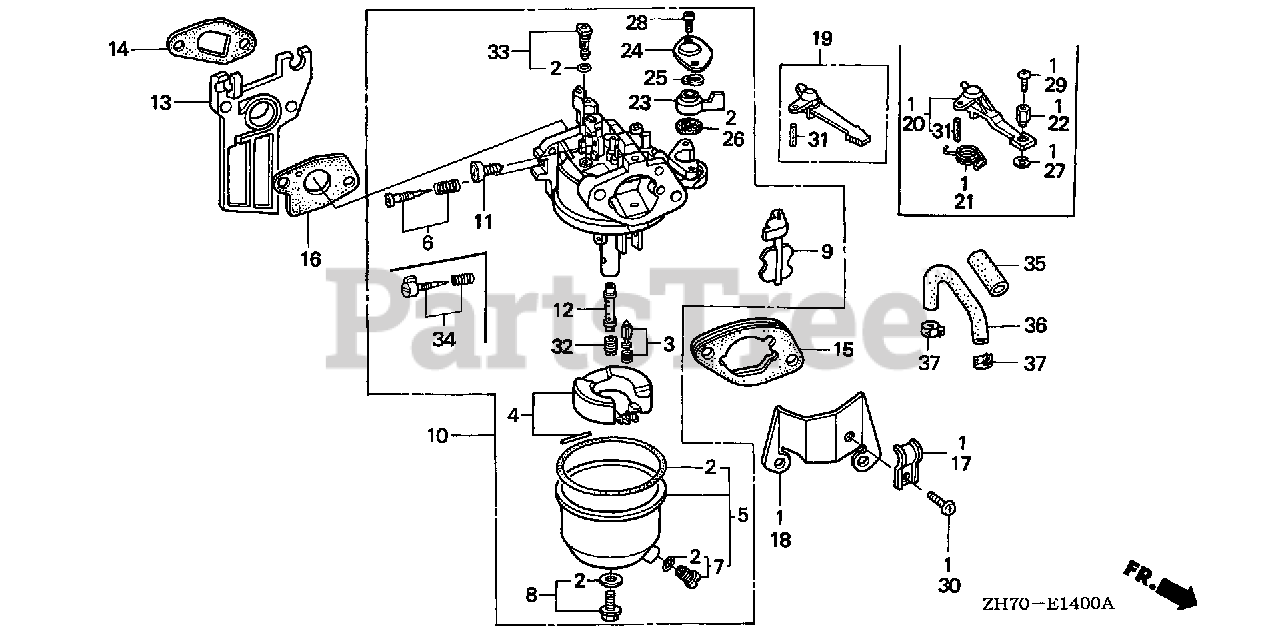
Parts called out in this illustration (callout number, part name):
2	GASKET SET
3	VALVE SET, FLOAT (SEAT NOT INCLUDED)
5	CHAMBER SET, FLOAT (CARBURETOR NO.)
6	SCREW SET, PILOT (CARBURETOR NO.)
7	SCREW SET, DRAIN
8	SCREW SET
9	CHOKE SET (CARBURETOR NO.)
10	CARBURETOR ASSY. (BE12B C)
11	SCREW, THROTTLE STOP
12	NOZZLE, MAIN (CARBURETOR NO.)
12	NOZZLE, MAIN
13	INSULATOR, CARBURETOR
14	GASKET, INSULATOR
15	SPACER, CARBURETOR
16	GASKET, CARBURETOR
19	LEVER, CHOKE (STD)
23	LEVER, PETCOCK
24	PLATE, LEVER SETTING
25	SPRING, PETCOCK LEVER
26	GASKET, PETCOCK
28	SCREW, PAN (3X6)
28	SCREW, PAN (3X8) (CARBURETOR NO.)
31	PIN, SPRING (2X12)
32	JET, MAIN (#55) (CARBURETOR NO.)
32	JET, MAIN (#58) (CARBURETOR NO.)
32	JET, MAIN (#60) (CARBURETOR NO.)
32	JET, MAIN (#58)
32	JET, MAIN (#60)
33	JET SET, PILOT (#35)
